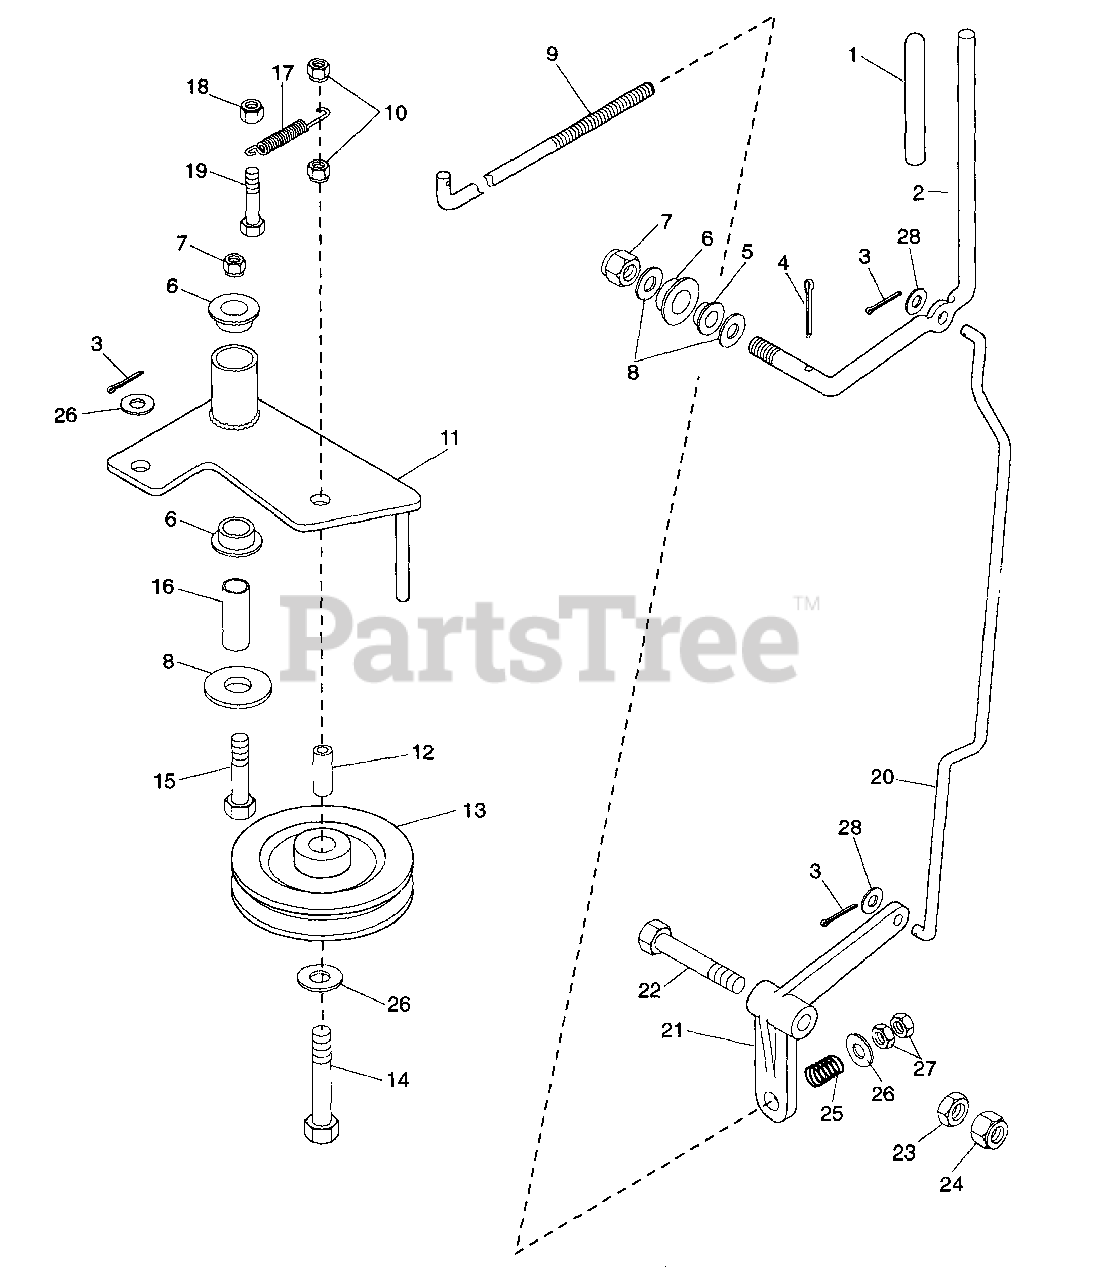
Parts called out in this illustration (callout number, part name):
1	Grip, PTO Lever
2	Lever, PTO Actuating
3	Pin-Cotter .09 x .75
4	Pin-Cotter .188 x 1.625
5	Bushing-Flange .515 x .750 x .745 x 1.00
6	Bushing-Flange .762 x 1.0 x .580 x 1.48
7	Nut-Locking-Nylon .50-13 Grade 5
8	Washer-Flat-Steel .531 x 1.250 x .100
9	Assembly, Tire/Wheel, Pro-100
10	Nut-Locking-Nylon .375-16 Grade 2
11	Declutch Arm-Pro PTO
12	Spacer .391 ID x .75 OD x 1.25
13	Idler-Pulley-Flat 3.25 x .625
14	Bolt-Hex .38-16 x 3.50 Grade 5
15	Bolt-Hex .50-13 x 3.50 Grade 5
16	Bushing for Declutch Arm Pivot
17	Spring-Tension .095 x .85 x 4.38
18	Nut-Locking-Nylon .312-18 Grade 2
19	Bolt-Hex .31-18 x 1.25 Grade 5
20	PTO Lever Link Rod, Pro 100
21	Lever, PTO Clutch
22	Bolt-Hex .50-13 x 2.50 Grade 5
23	Nut .50-13
24	Nut-Locking .50-13
25	Spring-Compression .125 x .78 x 1.00
26	Washer-Flat-Steel .406 x .812 x .065
27	Nut-Hex .375-16 Grade 2
28	Washer-Flat-Steel .344 x .688 x .065
